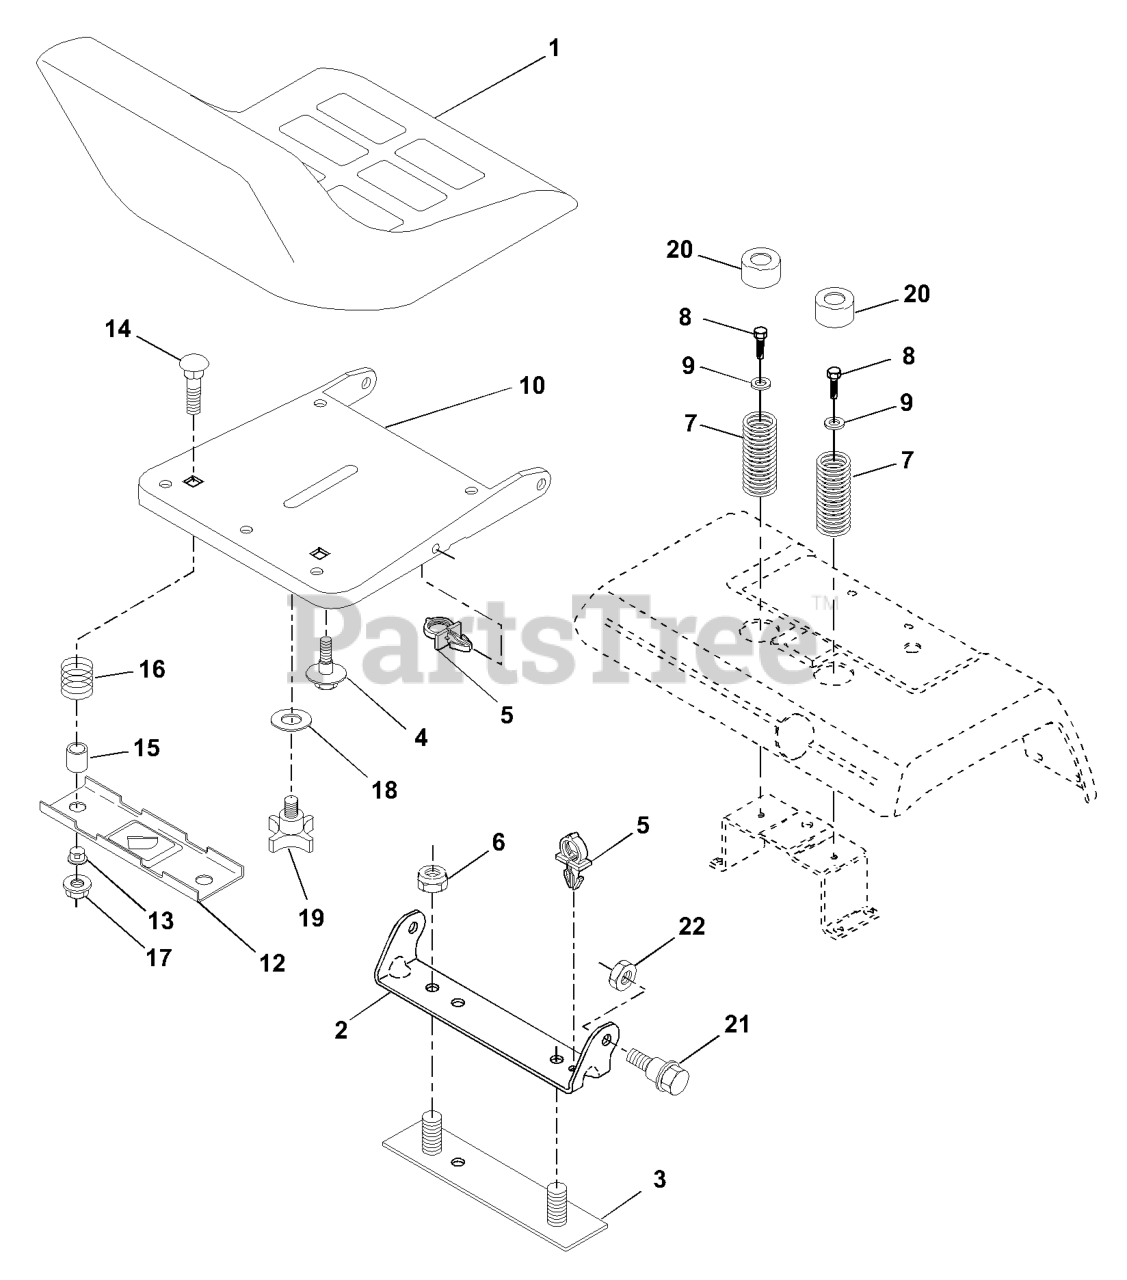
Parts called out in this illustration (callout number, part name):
1	SEAT
2	SEAT PIVOT BRKT
3	STRAP
4	BOLT,SHOULD
5	INSULATED CLIP
7	SPRING COMPRESSION
8	Screw, Thdrol 5/16-18 X 1/2
9	WASHER
10	SEAT PAN
12	BRKT SWITCH
14	Bolt, Carriage 1/4-20 X 1-3/8
15	SPACER SPLIT
16	SPRING COMPRESSED
17	NUT T
19	KNOB 1/2" YT
20	CAP SPRING
21	BOLT.SHOULDER.5/16-18
22	LOCKNUT
